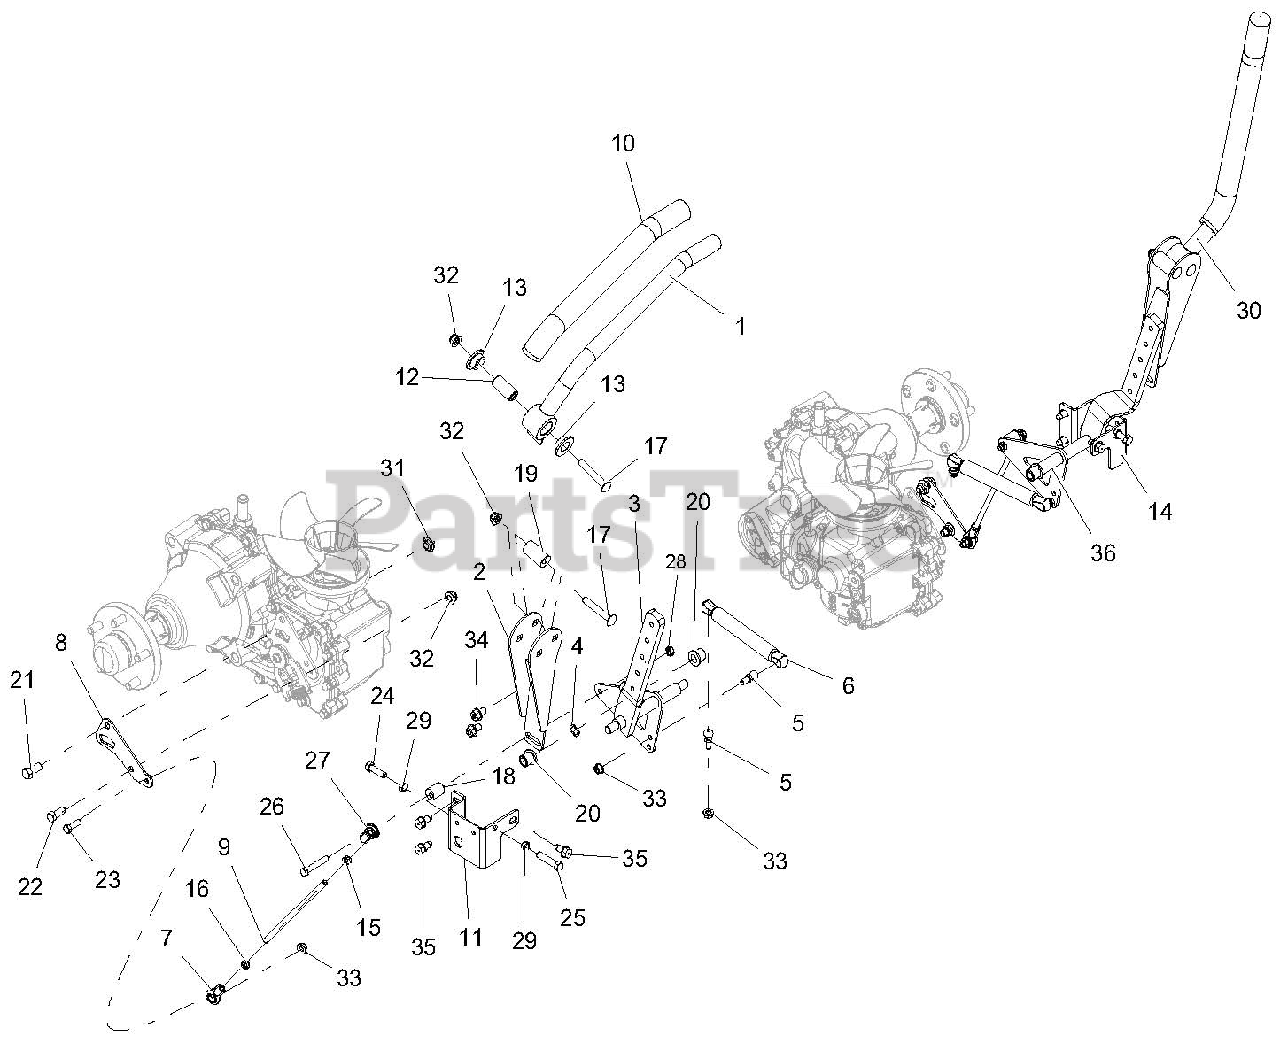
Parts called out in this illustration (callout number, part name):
1	WLDMT, RH CONTROL HANDLE
2	WLDMT, UPPER ADJUSTABLE CONTROL ARM
3	WLDMT, RH LOWER CONTROL ARM
4	WAVE WASHER .531X.781X.125 FH
5	STUD-BALL
6	DAMPER,
7	ALIGNABALL, 5/16 LH THREAD
8	BRKT., CONTROL MTG-BLACK
9	ROD, STEERING
10	GRIP, HANDLEBAR
11	BRKT, RH CONTROL ARM STOP
12	SPCR, STEERING ARM
13	BSHG, FLANGE .762 X 1.48 X .44 NYLON
14	BRKT, LH CONTROL ARM STOP
15	NUT-JAM
16	NUT, JAM -LH .31-24 YWZC
17	BLT-RHDSSQNK .38-16X2.50 G5YZ
18	ECCENTRIC
19	BSHG, ECCENTRIC .328 X .750 X 1.625
20	BHSG-FLG .500X.750X.750X.125
21	BLT-HEX .44-14X1.00 GR5 YWZC
22	BLT-HEX .38-16X1.00 GR5 YWZC
23	BLT-HEX .31-18X1.00 GR5 YWZC
24	BLT-HEX .38-16X1.25 GR5 YWZC
25	BLT-HEX .38-16X1.75 GR5 YWZC
26	BLT-HEX .31-18X2.00 GR5 YWZC
27	ALIGNABALL, 5/16 RH THREAD
28	NUT-LK-CTR .31-18 YWZC
29	NUT, JAM .375-16 YWZC
30	WLDMT, LH CONTROL HANDLE
31	NUT-LK-NYL-FLG .44-14 YWZC
32	NUT-LK-NYL-FLG .38-16 YWZC
33	NUT, LK-TOP-FLG .312-18 YWZC
34	BLT-SERHFWH .38-16X.62 YWZC
35	SCR-TAP .38-16X.75 HWH TR YWZ
36	WLDMT, LH LOWER CONTROL ARM
